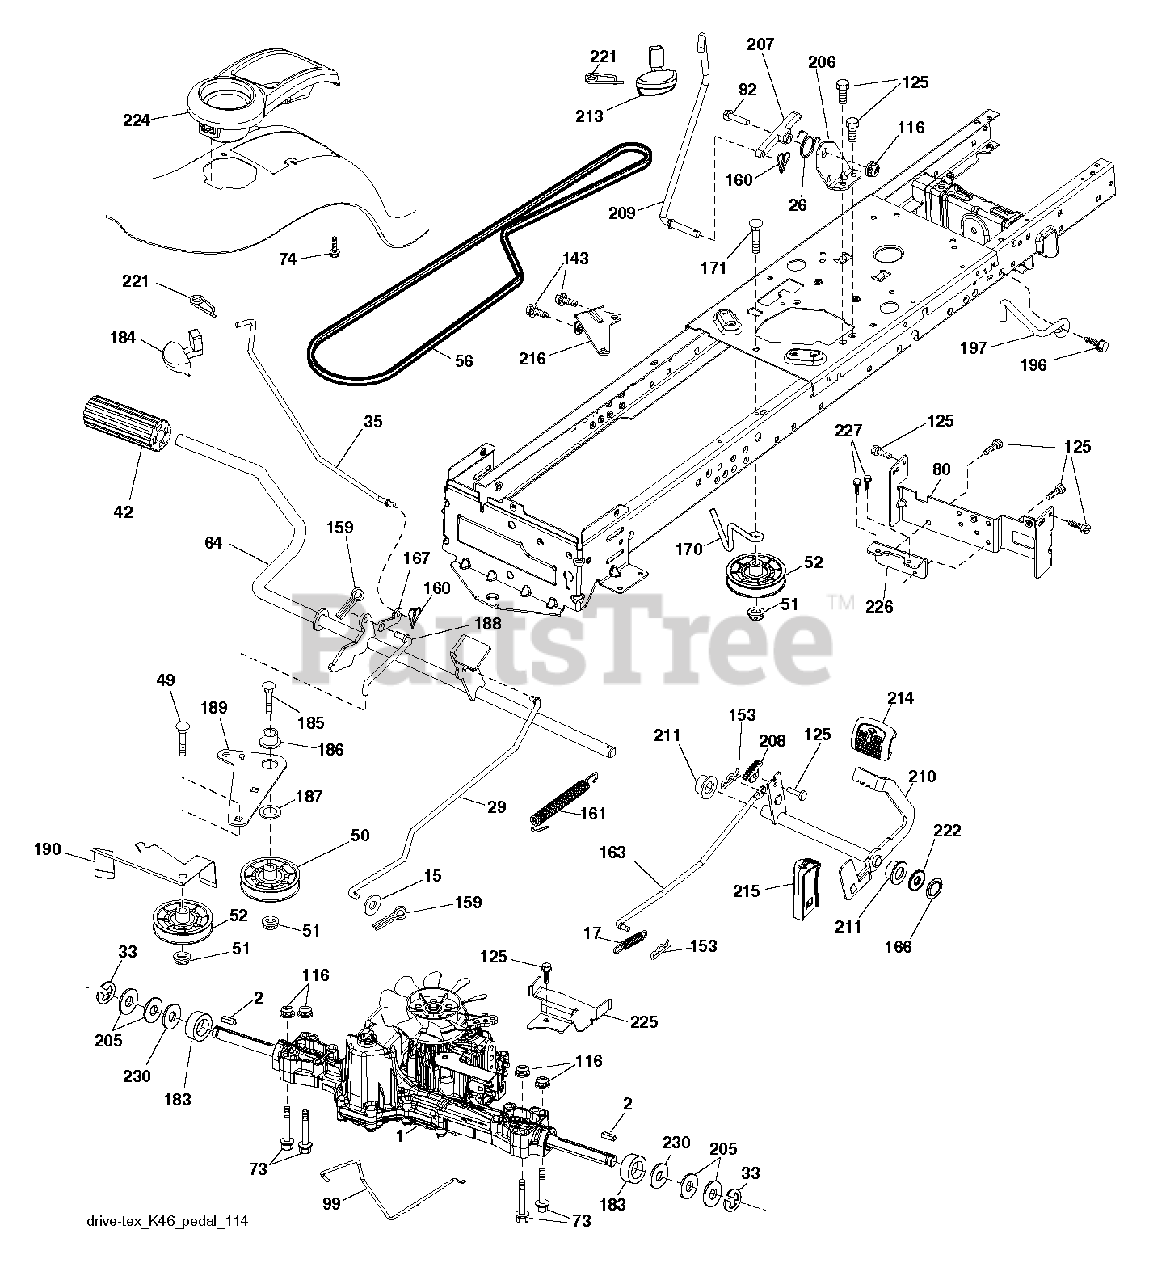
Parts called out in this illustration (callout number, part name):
2	SQUARE KEY
17	SPRING.BRAKE.K46.GREEN
26	SPRING.RETURN.CRUISE
29	ROD.BRAKE.K46
33	E-RING LT
35	Parking Brake Rod, GT Husq
42	PEDAL COVER T
49	BOLT
50	IDLER.FLAT.910.OFFSET
51	NUT LOCK FLG 3/8-16 UNC
52	IDLER.V-GROOVE.910.OFFSET
64	SHAFT.ASM.PEDAL.BRK.CNTR
74	SCREW.HI-LO.CONSOLE
80	STRAP.TORQUE.K46.K57R.TT
92	BOLT
99	ROD.SPRING.BYPASS.K46.LT.Z
116	NUT LOCK HEX FLANGE 5/16-18
125	SCREW
153	RETAINER M
159	COTTER PIN
160	RETAINER CLIP
161	SPRING, RETURN LT
163	ROD.CONTROL.PEDAL.K46
166	NUT.PUSH.625
167	LATCH.BRAKE.SPRING
170	KEEPER.CENTER SPAN.1.688
171	BOLT
183	SPACER AXLE
184	HANDLE.PARKG.BRK.HUSQ/PRED.667
186	SPACER.RETAINER
187	WASHER 12/32X2X10GA
188	LINK.CLUTCH.GROUND.DRIVE
189	BELLCRANK.GROUND.DRIVE.TEX.
190	KEEPER.BELLCRANK.DRIVE
196	SCREW 3/8-16X1
197	LINK.CLUTCH.ANIT-ROTAT
207	LATCH.CONTROL.CRUISE
208	GEAR.SECTOR.CONTROL.CR
209	ROD.CONTROL.CRUISE.GT.
210	ROCKER.ASM.PEDAL.CONTR
211	BEARING.NYLON
213	KNOB.CONTROL.CRUSIE.HU
214	PAD PEDAL FORWARD
215	PEDAL.REVERSE.TEX.GT.4
216	BRACKET.PULLEY.IDLER.W/TEX
221	RETAINER.SPRING.CLIP.H
222	WASHER 21/32 X 1-1/4 X 10 GA.
224	CONSOLE.TOOLBOX.PCH.ERGO.BLACK
225	KEEPER.BELT.TRANSAXLE.K46
226	BRACKET.MOUNT.TORQUE.K46.TLT
227	SCREW
230	WASHER.HARDENED
